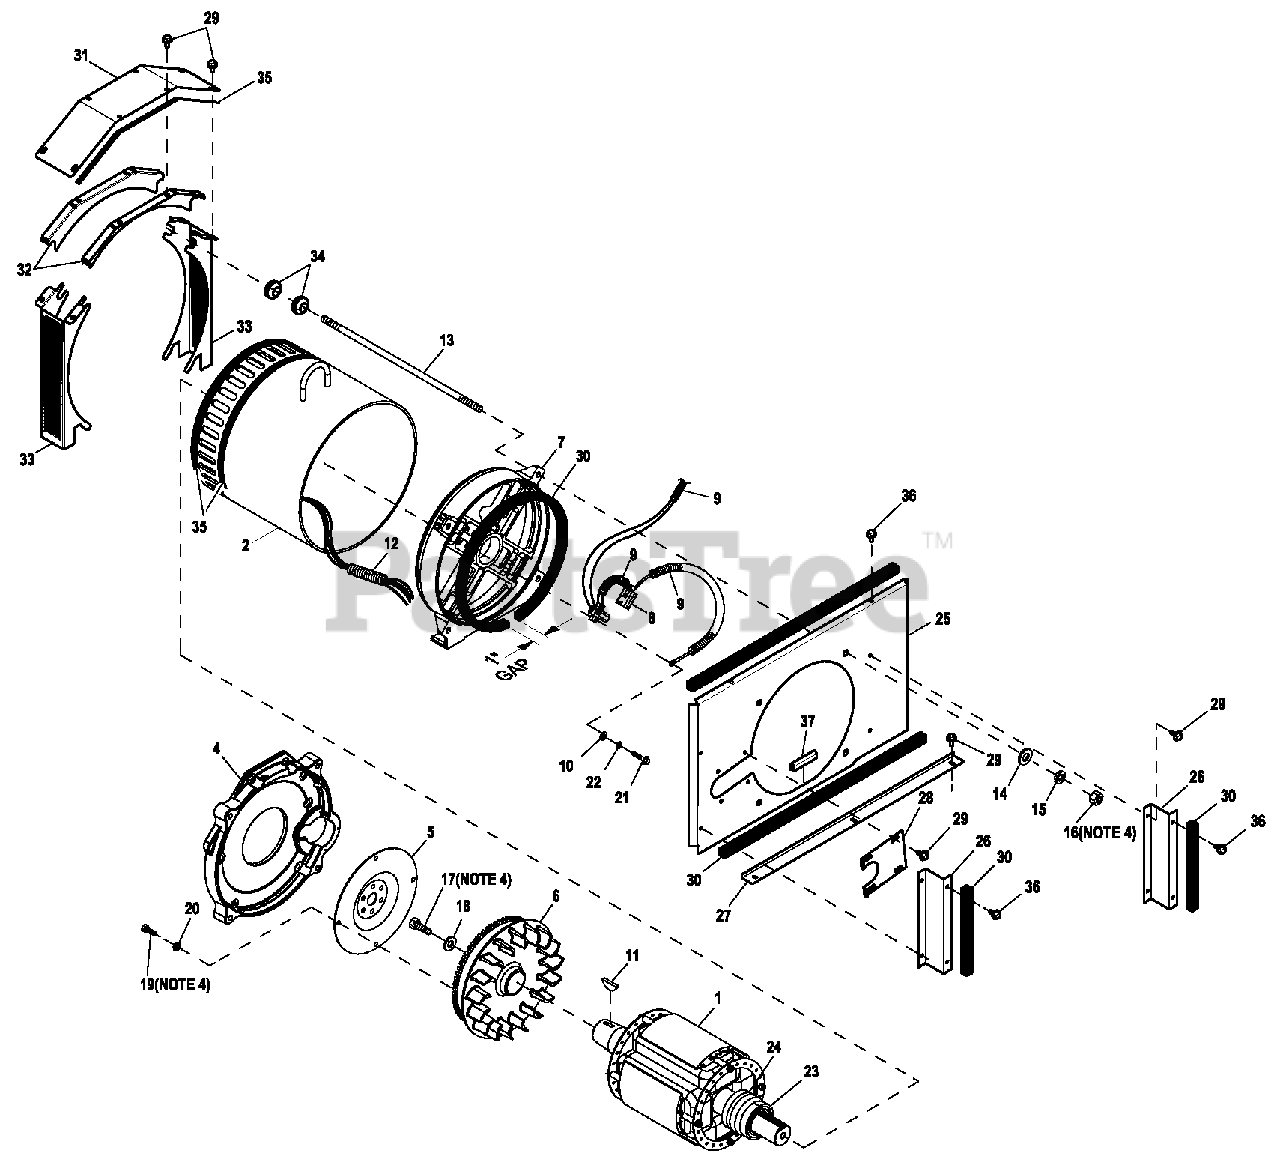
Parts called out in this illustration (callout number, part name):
1	ROTOR 25KW 3PH DIRECT 390 1800
2	ASSY STR 390 25 GD1 CPL
4	ENGINE ADAPTER
5	FLEXPLATE
6	ASSY FLYWHEEL CPL W/40MM FAN B
7	REAR BEARING CARRIER 390/DRCT
8	ASSY BRUSH HOLDER 390/HSB
9	CONDUIT FLEX .38" ID (60")
10	WASHER FLAT #8 ZINC
11	KEY WOODRUFF #E
12	CONDUIT FLEX 1.25"ID (35" LG)
13	STUD M14-2.0 570 G5ZINC
14	WASHER FLAT M14
15	WASHER LOCK M14
16	NUT HEX M14-2.0 G8 YELCHR
17	SCREW HHC M16-2.0X 45 G8.8
18	SPACER .69 X 2.75 X .37 ST/ZNC
19	SCREW HHC M10-1.5X 25 C10.9
20	WASHER LOCK M10
21	SCREW HHTT M4-0.7 X 25 BP
22	WASHER LOCK #8-M4
23	BALL BEARING-45 MM
24	SLIP RING MACHINED
25	BLOCK OFF, ALTERNATOR AIR
26	BLOCK OFF,ALTAIRLH/RH
27	BAFFLE-ALT INLET
28	PLATE LEAD CLAMP
29	SCREW HWHT M6-1 X 16 N WA Z/JS
30	TAPE FOAM 1X1 (166" LG)
31	SCROLL TOP 390 ALT CPL
32	SCROLL FT/RR 390 ALT CPL
33	SCROLL LH/RH 390 ALT CPL
34	GROMMET .7 5X .1 2X .5 0
35	FOAM STRIP 3/4"WIDE X 1/4"THK (120"LG)
36	SCREW PHTT M5-0.8X 16 ZP
37	TRIM VINYL BLACK 1/8GP (10" LG)
